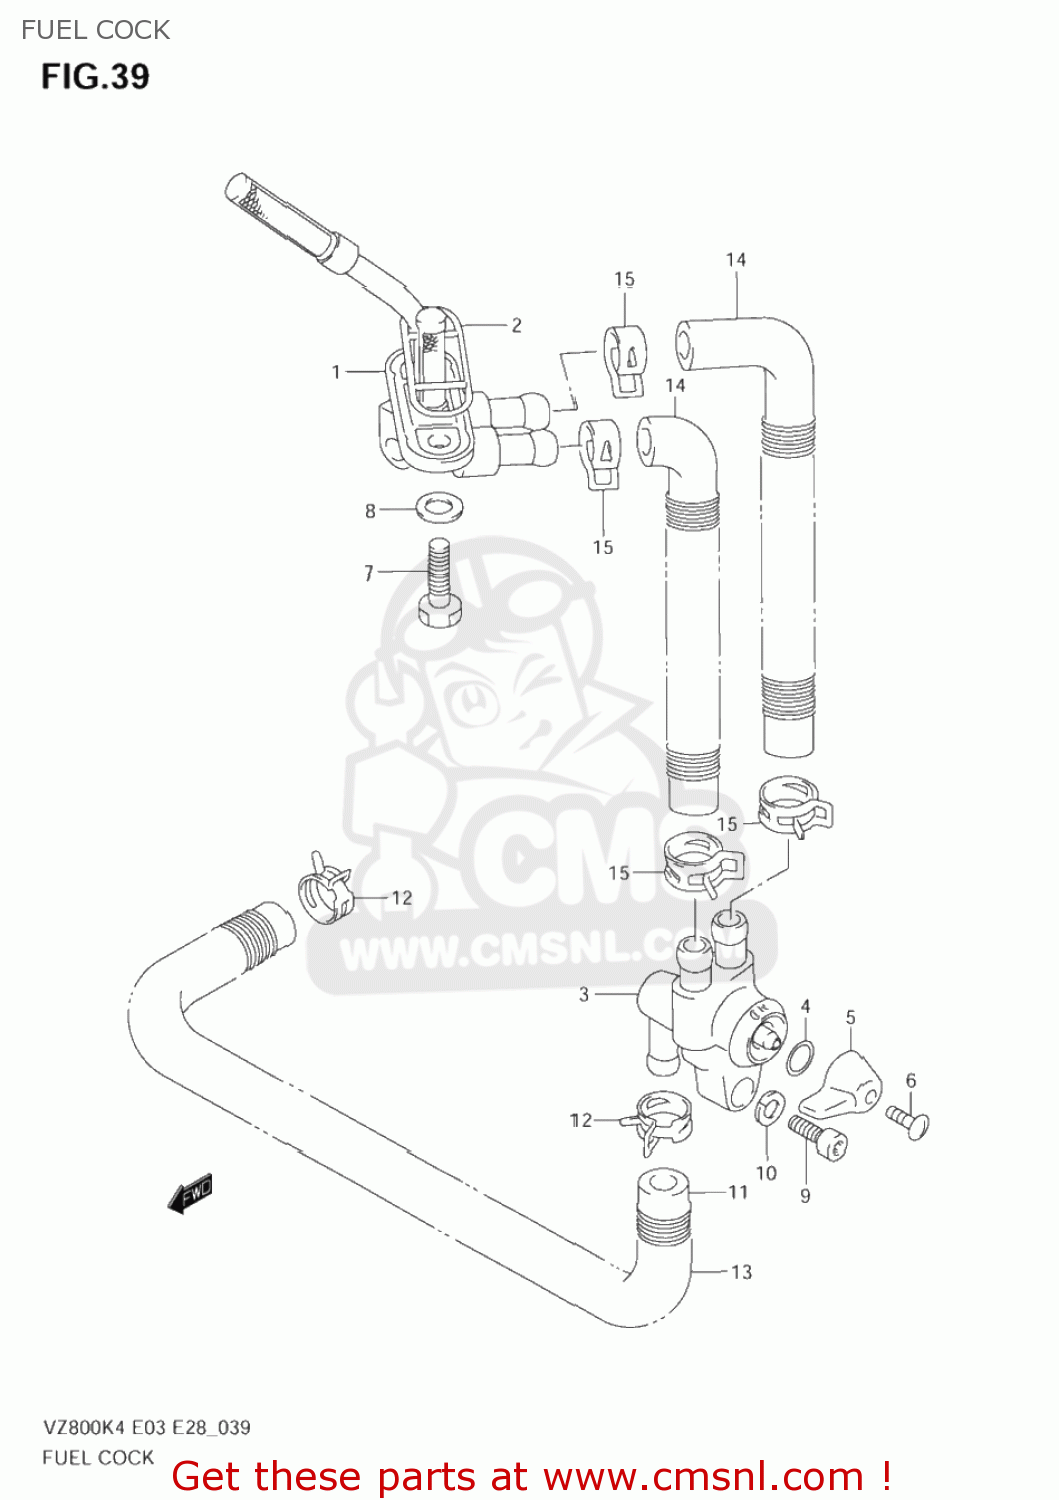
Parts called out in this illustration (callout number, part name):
1	FILTER UNIT,FUEL
2	GASKET,JOINT (NAS)
3	COCK ASSY,FUEL
4	O RING,LEVER
5	LEVER,FUEL COCK
6	SCREW,COCK LEVER
7	BOLT(6X20)
8	GASKET(6.4X11.5X0.8) (NAS)
9	BOLT(5X12)
10	LOCK,WASHER
11	HOSE,FUEL
12	CLIP
13	SPRING
14	HOSE,FUEL FILTER/COCK
15	CLIP
